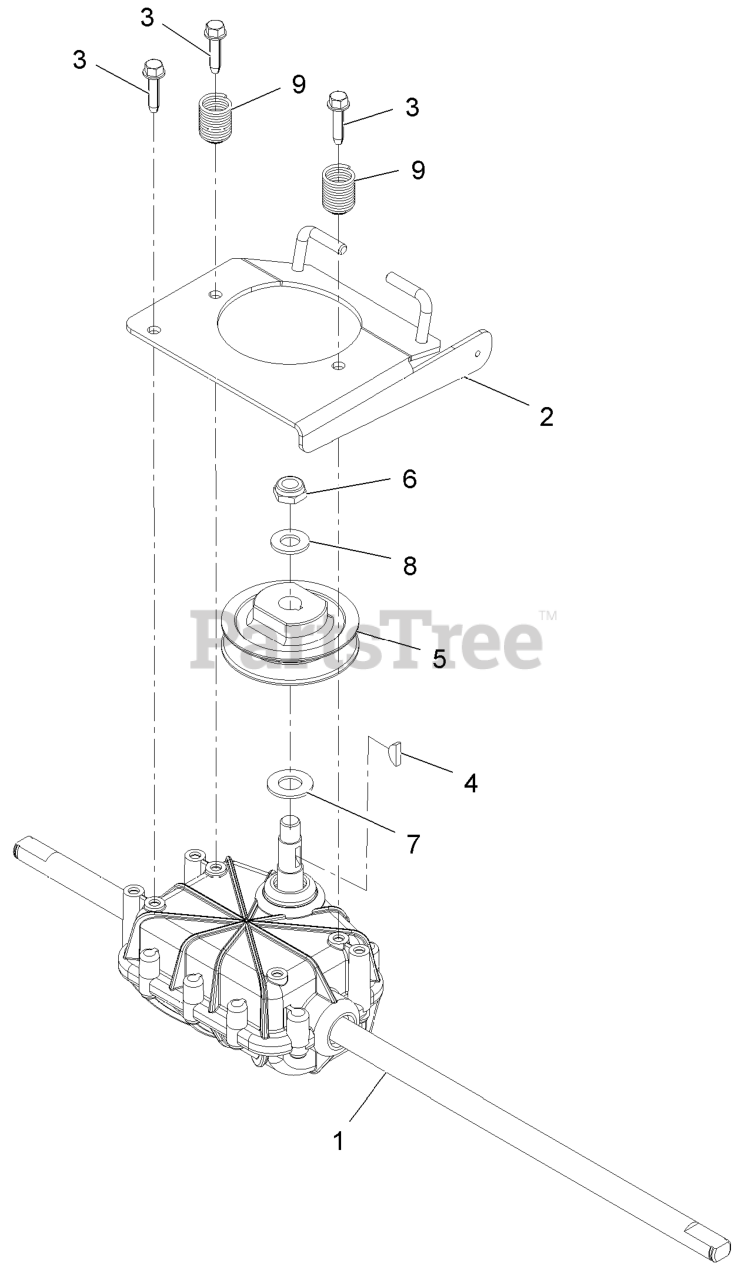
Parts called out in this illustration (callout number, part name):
2	TRANSMISSION PLATE ASM
3	SCREW-SPECIAL
4	KEY-WOODRUFF
6	NUT-HEX
7	WASHER-THRUST
8	WASHER-FLAT
9	SPRING,COMPRESSION
